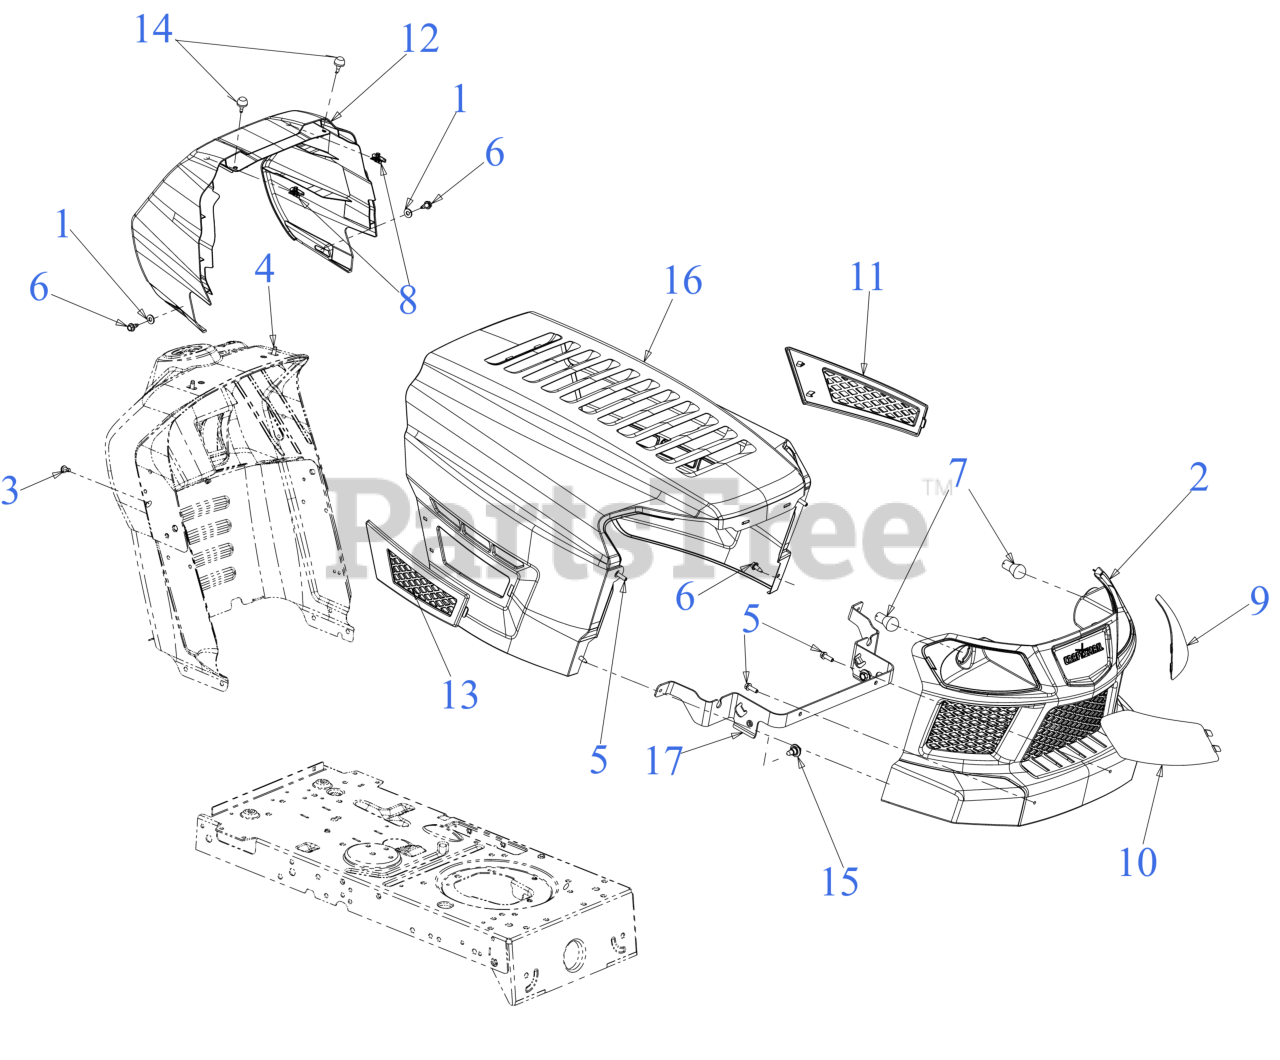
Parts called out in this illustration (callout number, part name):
1	FLAT WASHER 1/4 SAE ZINC
2	GRILLE
3	SCREW 1/4-20 x .5
4	SCREW 1/4-20 x .750
5	SCREW 1/4-15 x .750
6	SCREW 1/4-20X.625
7	MINIATURE LAMP-12V #1156
8	U-CLIP NUT
9	GRILLE LENS (LH)
10	GRILLE LENS (RH)
11	SIDE COVER (LH)
12	DASH COLLAR
13	SIDE COVER (RH)
14	BUMPER
15	SHOULDER SCREW .43X.29X5/16-18 TT
